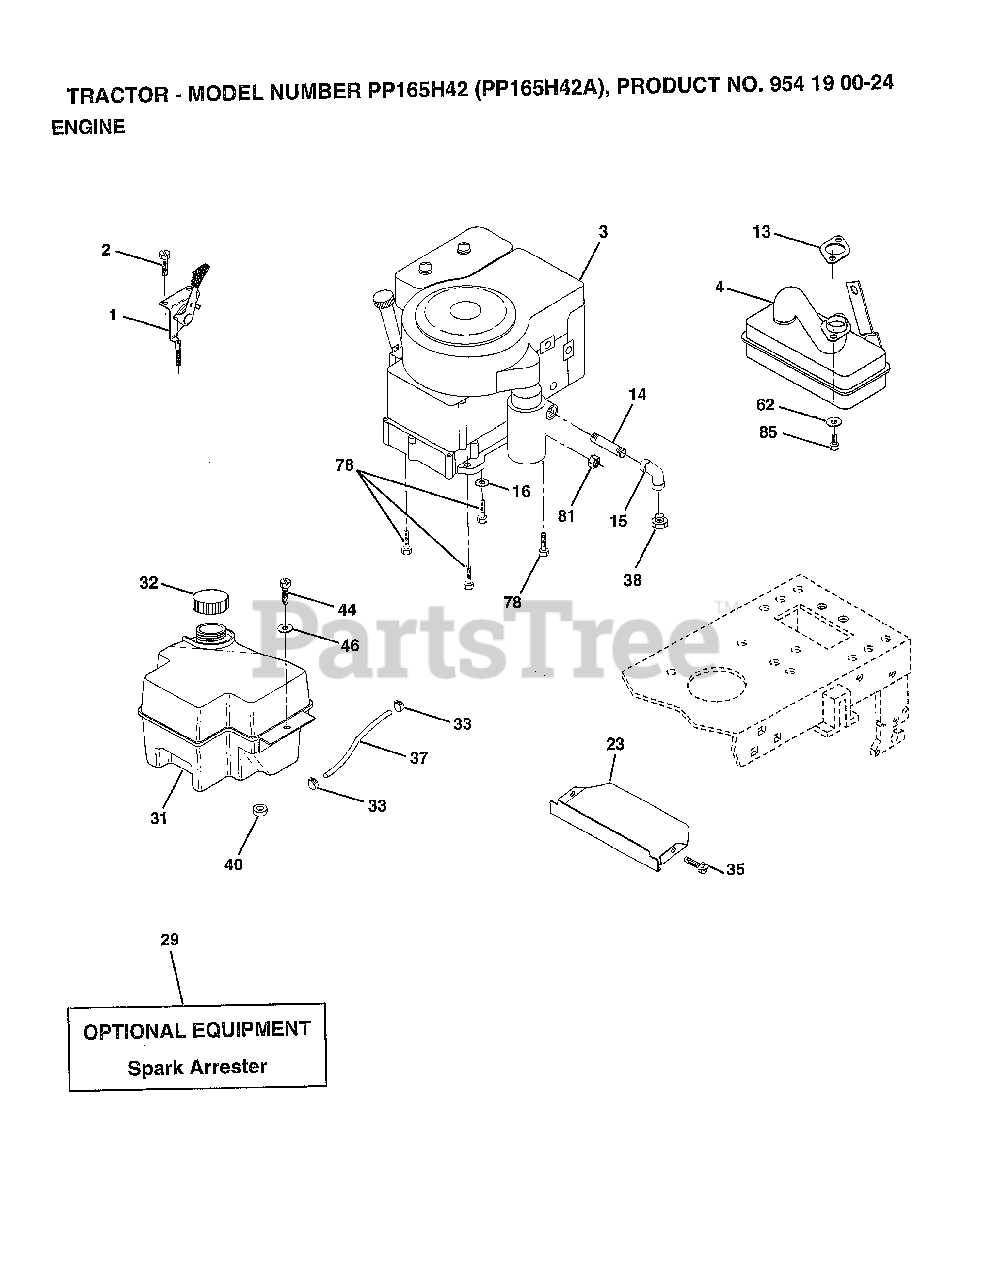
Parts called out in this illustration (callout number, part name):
1	CONTROL THROTTLE
2	SCREW LT
4	MUFFLER
13	GASKET MUFFLE TEC
14	PIPE NIPPLE LT
15	ELBOW
16	LOCKWASHER
23	SHIELD.BRN/DBR.GD
31	TANK.FUEL.FRONT.
32	CAP ASM FUEL
33	HOSE CLAMP
35	SCREW
37	LINE FUEL
44	SCREW HEX CRT
46	WASHER
62	LOCKWASHER
78	SCREW
81	NUT
85	SCREW HEX HD CAP
